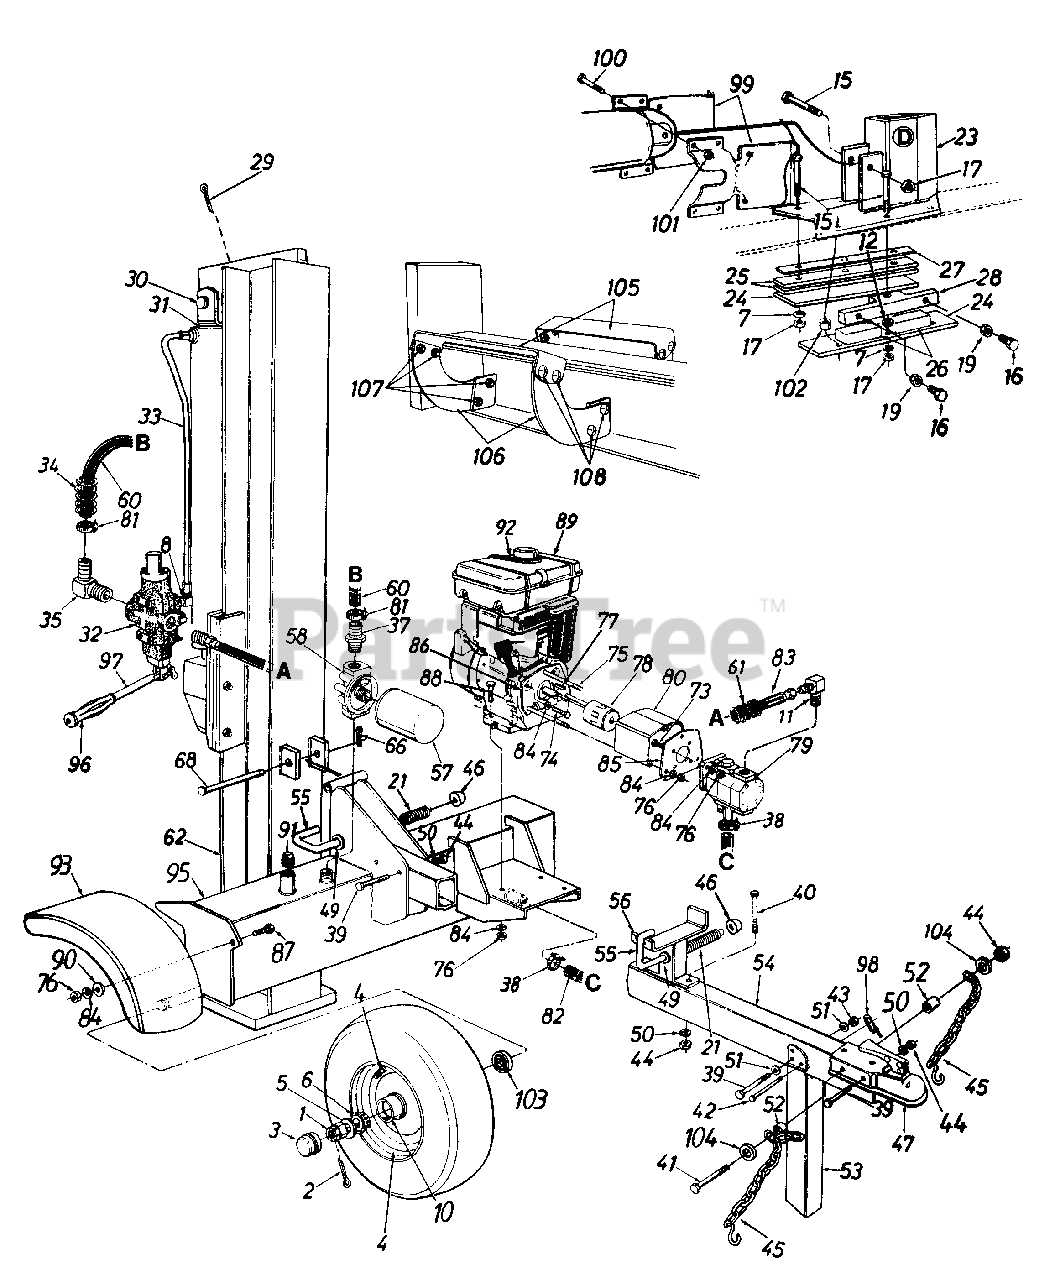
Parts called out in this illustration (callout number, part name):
1	Slotted Nut 3/4-16 Thd.
2	Cotter Pin 5/32" Dia.
3	Hub Cap
5	Fl-Wash. .76" I.D. x 1.5" O.D.
6	Bearing Cone
7	L-Wash. 1/2" I.D.
10	Bearing Cup
11	90ø Male Adapter
12	Fl-Wash. .531" I.D. x .94" O.D.
15	Hex Bolt 1/2-20 x 2.75" Lg. (Grade 8)
16	Hex Bolt 3/8-24 x 1.5" Lg.
17	Hex L-Nut 1/2-20 Thd.
19	Hex Jam Nut 3/8-24 Thd. (Grade 5)
21	Comp. Spring 4" Lg.
26	Adjustable Gib
29	cotter Pin
30	Cylinder Mounting Pin
33	Metal Pressure Tube
34	Hose Guard
35	Return Elbow
37	3/4" Hose Barb.
38	Hose Clamp
39	Hex Bolt 3/8-16 x 3" Lg. (Grade 8)
40	Hex Bolt 3/8-16 x 4" Lg.
41	Hex Bolt 3/8-16 x 4.25" Lg. (Grade 5)
42	Clevis Pin 5/16 x 2.5" Lg.
43	Hex L-Nut 3/8-16 Thd.
44	Hex Nut 3/8-16 Thd.
45	Chain--Tow Hitch
46	Push Cap
47	Hitch Coupler
49	Fl-Wash. .635" I.D. x .93" O.D.
50	L-Wash. 3/8" I.D.
51	Fl-Wash. .406" I.D. x .75" O.D.
52	Spacer .44" Lg.
55	Locking Rod
57	filter Element
58	Filter Head
60	Return Hose 3/4" I.D. x 44" Lg.
61	Hose Guard
68	Hinge Pin 1/2 x 4.8" Lg.
73	Hex Bolt 5/16-24 x 1" Lg.
74	Hex Bolt 5/16-24 x .62" Lg.
75	Hex Bolt 5/16-24 x 4" Lg.
76	Hex Nut 5/16-24 Thd.
77	Sq. Key 3/16" x .75"
78	Flexible Coupling
79	Gear Pump
80	Coupling Shield
81	Hose Clamp 5/8"
82	Suction Hose
83	High Pressure Hydraulic Hose 48"
84	L-Wash. 5/16" I.D.
87	Hex Bolt 5/16-24 x .75" Lg.
88	Hex Bolt 5/16-24 x 1.75" Lg.
89	Engine
90	Fl-Wash. .344" I.D. x .875" O.D.
91	L-Vent Pipe Plug
92	Spark Plug Boot
97	Control Handle
98	Spring Pin
101	Nut 3/8-26 Nylon Lock
102	Spacer 1/2" I.D. x .86" Lg.
103	Bearing seal Only
104	Fl-Wash. 3/8" I.D. x .87" O.D.
108	Carriage Bolt 3/8-16 x 1" Lg.
